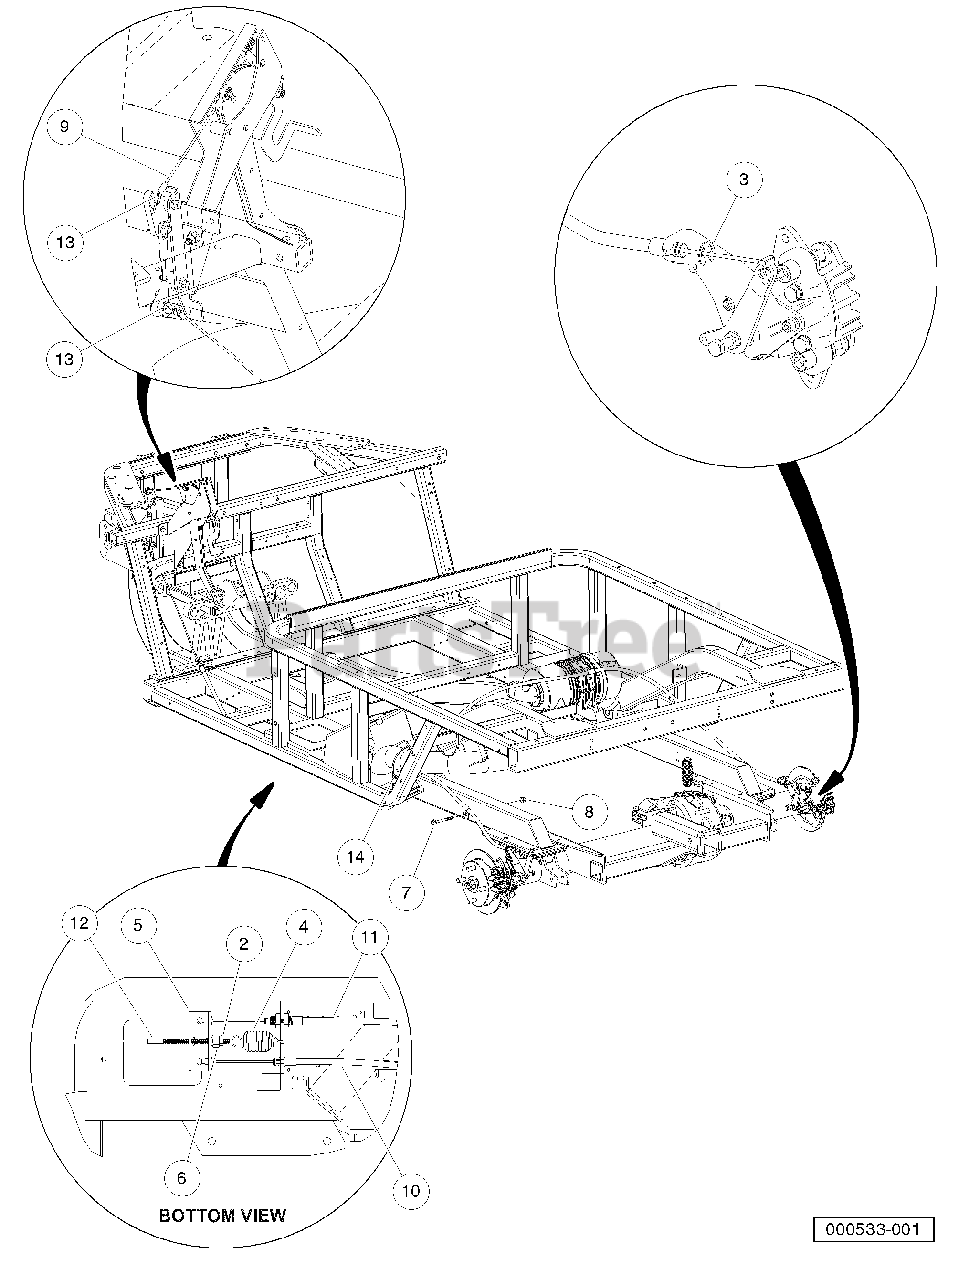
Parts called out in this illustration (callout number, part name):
1	Instl, Brake, Park, AWD
2	Nut, 5/16-24 Hex
3	E-Clip, 1/2
4	Spring, Brake Return
5	Equalizer Bracket
6	Nut, 5/16-24 Hex Cone
7	Bolt Flanged Head, M8 X 1.25 X 65
8	Lock Nut, Flg M8 X 1.25 Nylon
9	Cable, Crank, Bell, Front
10	Cable, Noncoated, Pbrake, Left
11	Cable, Noncoated, Pbrake, Rght
12	Cable, Crank, Bell, Main
13	Pin, 3/32 X 1.00 Sq Cut Cotter
14	Tie Wrap, 11" Nylon
